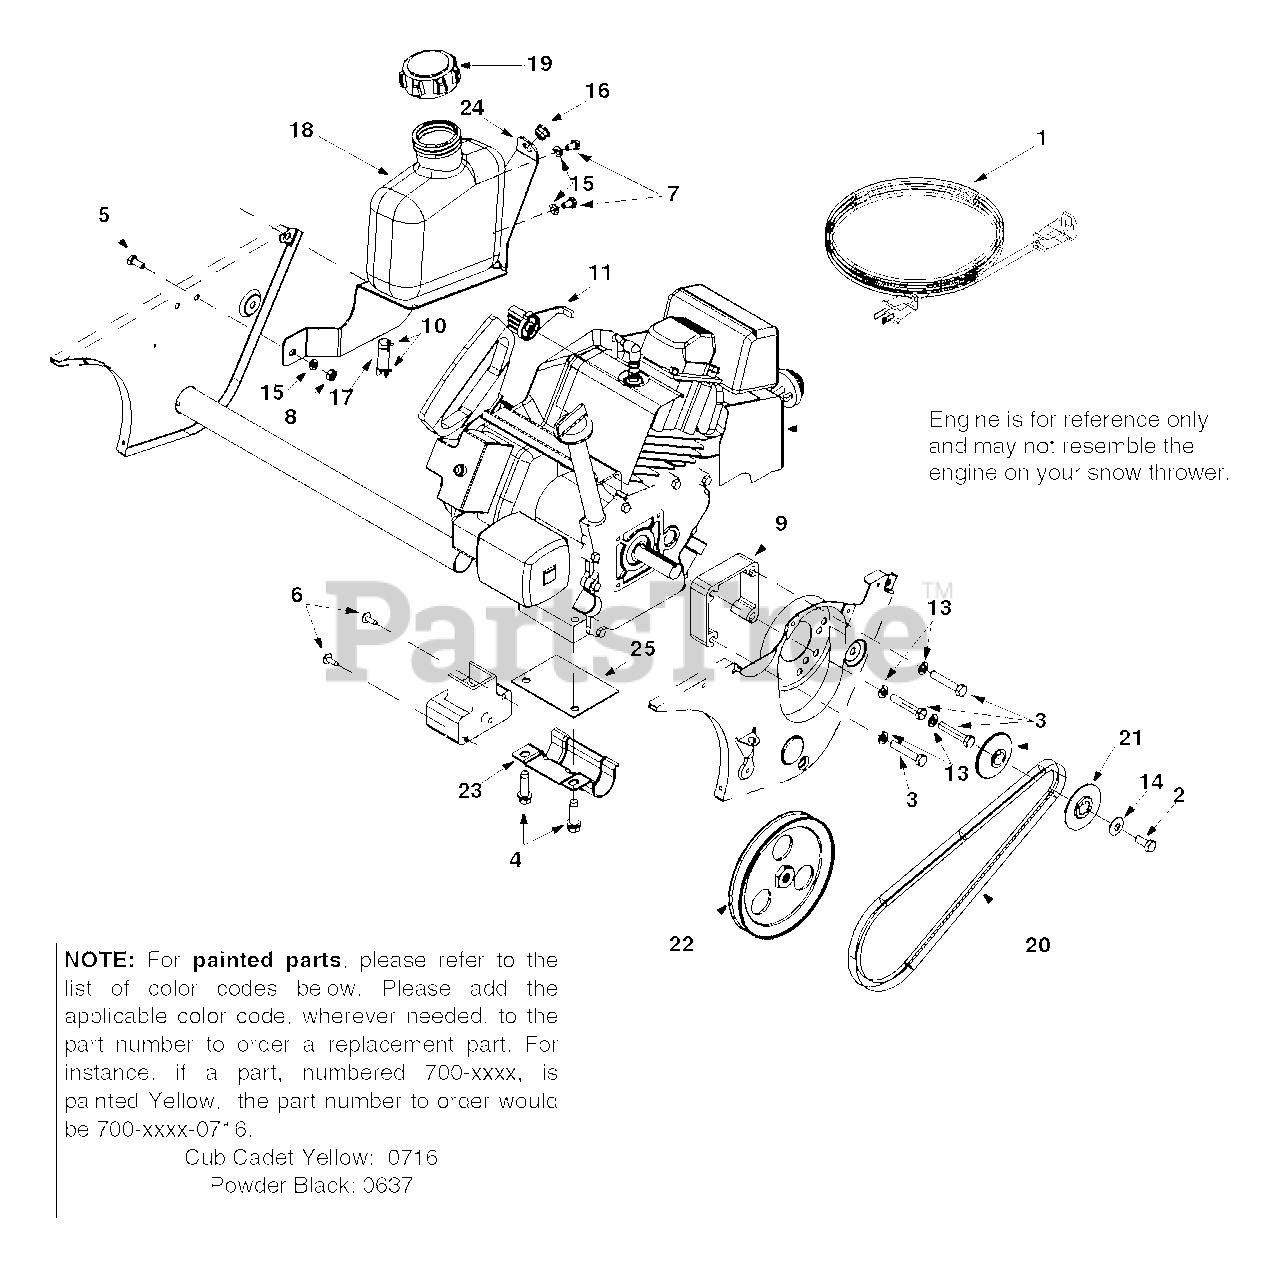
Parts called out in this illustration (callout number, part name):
1	Extension Cord
2	Hex Bolt 5/16-24 x 0.75"
3	Hex Bolt 5/16-24 x 1.75"
4	TT Sems Screw
5	Hex Screw 1/4-20 x 0.620"
6	B Screw #10-16 x 0.625"
7	Hex Screw 1/4-20 x 0.50"
8	Hex Nut 1/4-20
10	Hose Clamp
11	Choke Knob
13	Lock Washer
14	Beleville Washer
15	Lock Washer
16	Plastic Bushing
17	Fuel Line Hose
19	Fuel Cap
20	V-Belt
21	V-Pulley Half
